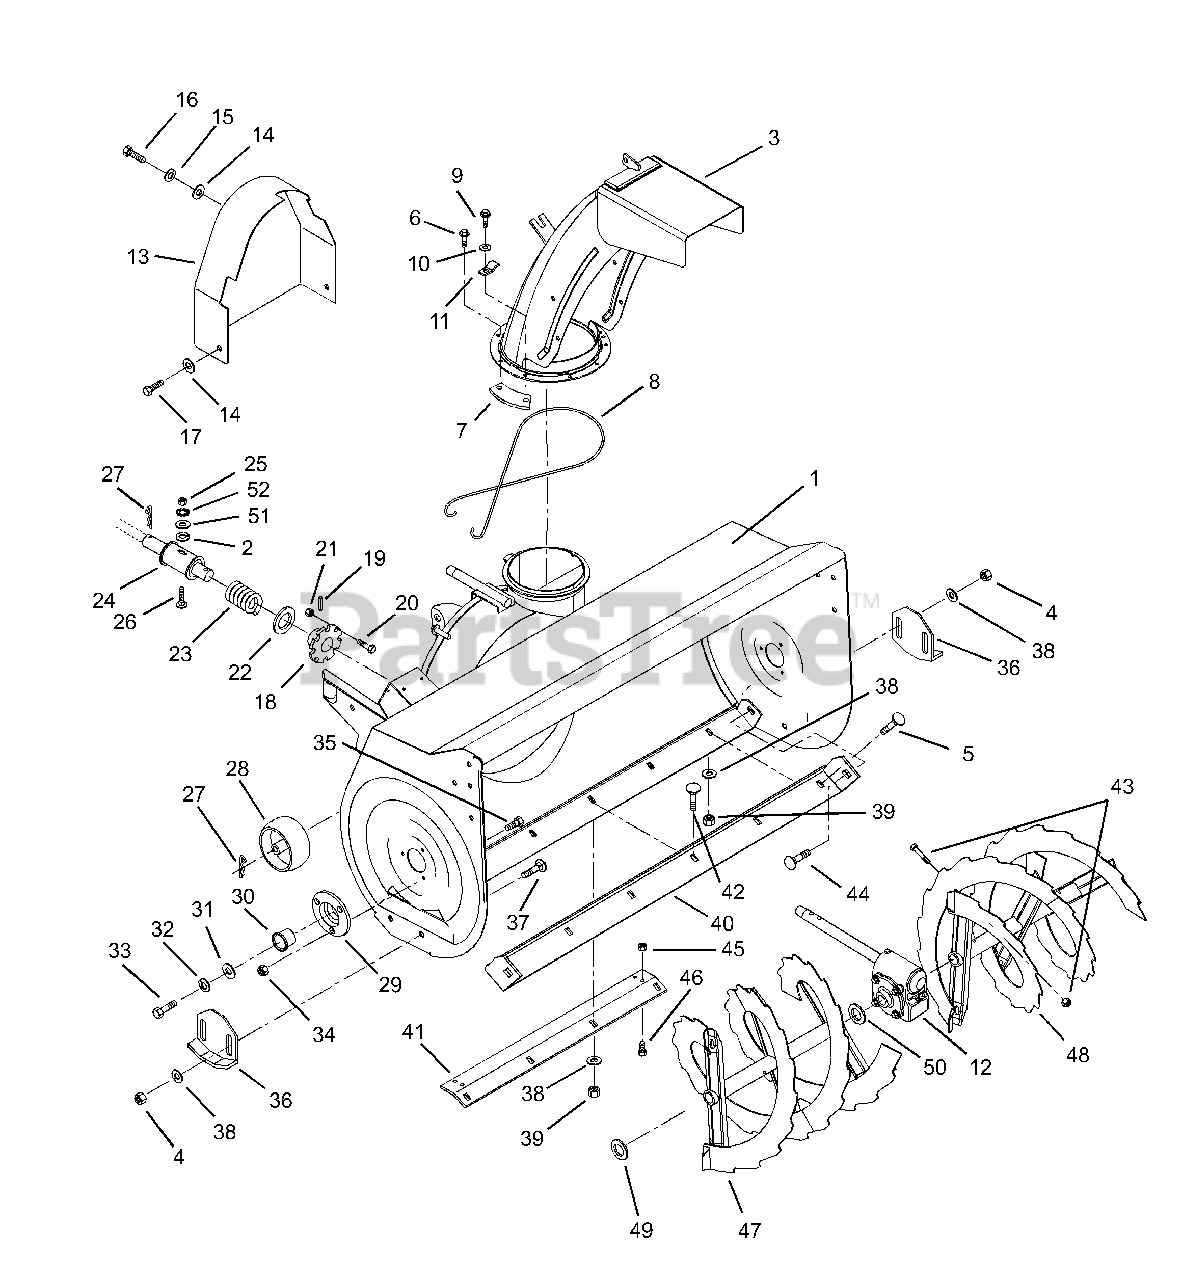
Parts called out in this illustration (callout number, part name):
1	40" Sno-Thro Housing
1	36" Sno-Thro Housing
2	Washer-Lock .31 x .062
3	Chute, Discharge w/ Cap & Decal
4	Nut-Locking .375-16
5	Bolt-Round Head Square Neck .31-18 x .75 Grade 5
6	Screw-Tapping 12-24 x .50 Hex Washer Head
7	Chute Clamp
9	Screw-Tapping 12-24 x .75 Hex Washer Head
10	Washer-Flat-Steel .188 x .438 x .049
11	Cable Clamp
12	Blower Gearcase Assembly
13	Belt Guard
14	Washer-Flat-Steel .382 x .812 x .062
15	Washer-Lock .312 x .097
16	Bolt-Hex .31-18 x .75 Grade 5
17	Screw-Tapping .312-18 x .50
18	Disc Assembly
19	Pin-Roll .188 x 1.00
20	Screw-Socket Head 10-24 x .38
21	Nut-Locking Dual Face 10-24
22	Washer-Flat-Steel .656 x 1.31 x .095
23	Spring-Compression .054 x .75 x 1.6
24	Spool
25	Nut-Hex .25-20
26	Bolt-Round Head Square Neck .25-20 x .75 Grade 5
27	Pin-Hair Internal .08 x .38 x 1.42
28	Roller
29	Bearing Support
30	Bushing-Flange 1.000 x 1.12 x .62 x 1.50
31	Washer-Flat-Steel .511 x 1.441 x .125
32	Washer-Lock .500 x .151 Heavy
33	Bolt-Hex .50-13 x 1.00 Grade 5
34	Nut-Locking-Flange .250-20
35	Bolt-Serrated Neck Slotted .25-20 x .50
36	Runner-Skid Shoe
37	Bolt-Round Head Square Neck .38-16 x .75
38	Washer-Flat-Steel .38 x .875 x .083
39	Nut-Locking .312-18
40	Scraper Blade
41	Blade Brace
42	Bolt-Round Head Square Neck .31-18 x 1.00 Grade 5
43	Shear Bolt Service Assembly
44	Bolt-Round Head Square Neck .38-16 x 1.0 Grade 5
45	Nut-Locking-Center .375-16
46	Bolt-Hex .38-16 x .75 Grade 5
47	Rake-Right Hand
48	Rake-Left Hand
49	Washer-Flat-Steel 1.010 x 1.505 x .062
50	Seal 1.625 x 2.125 x .250
51	Washer-Flat-Steel .281 x .620 x .065
52	Washer-Locking-External .262 x .502 x .026
